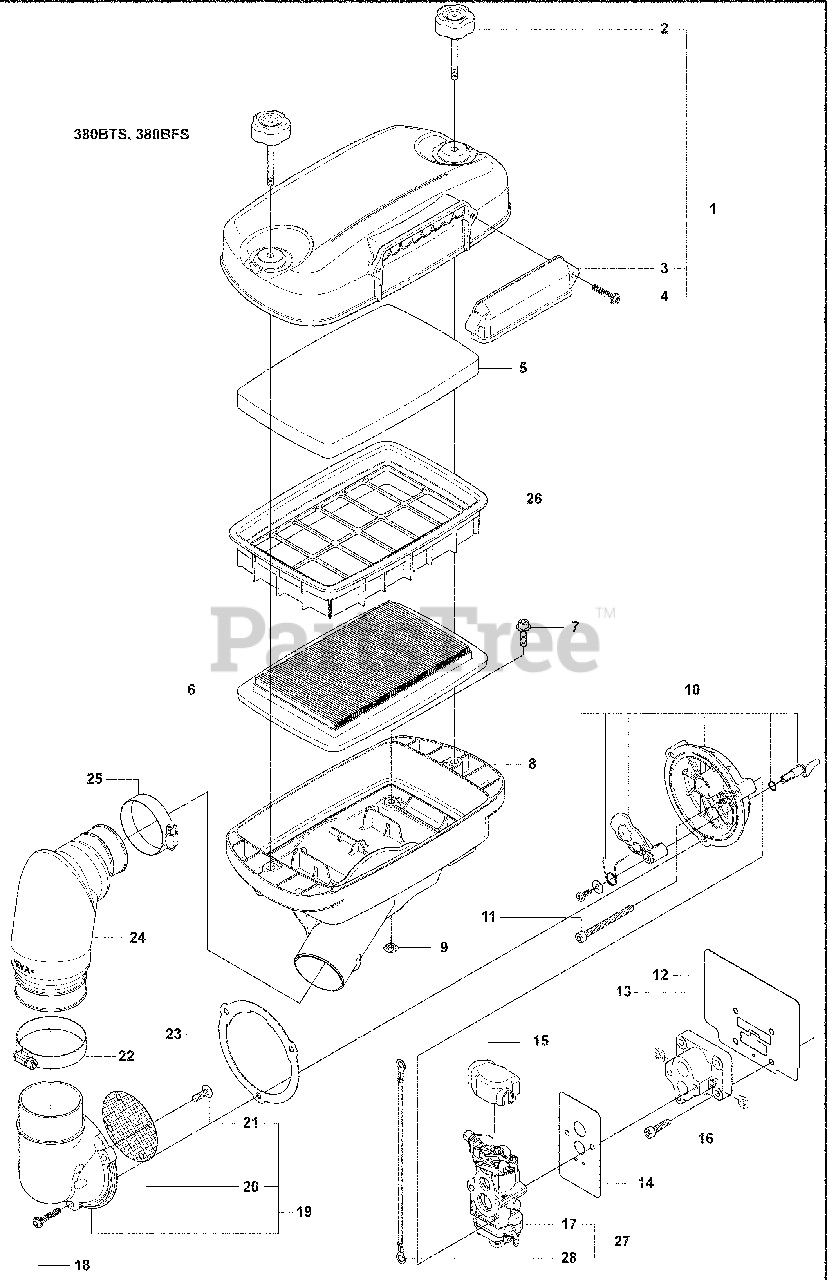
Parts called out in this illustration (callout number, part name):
1	Cover Assembly
4	Screw
5	Air Filter Element
6	Air Filter Element
7	Bolt
10	Cup Assembly
11	Bolt
12	Gasket
13	Insulator
14	Gasket
15	Cover
16	Bolt
17	Carburetor Assembly
18	Screw
19	Cup Cover Assembly
21	Screw
22	Clamp, F64
23	Gasket
25	Clamp, F64
27	Carburetor Set
28	CORD
